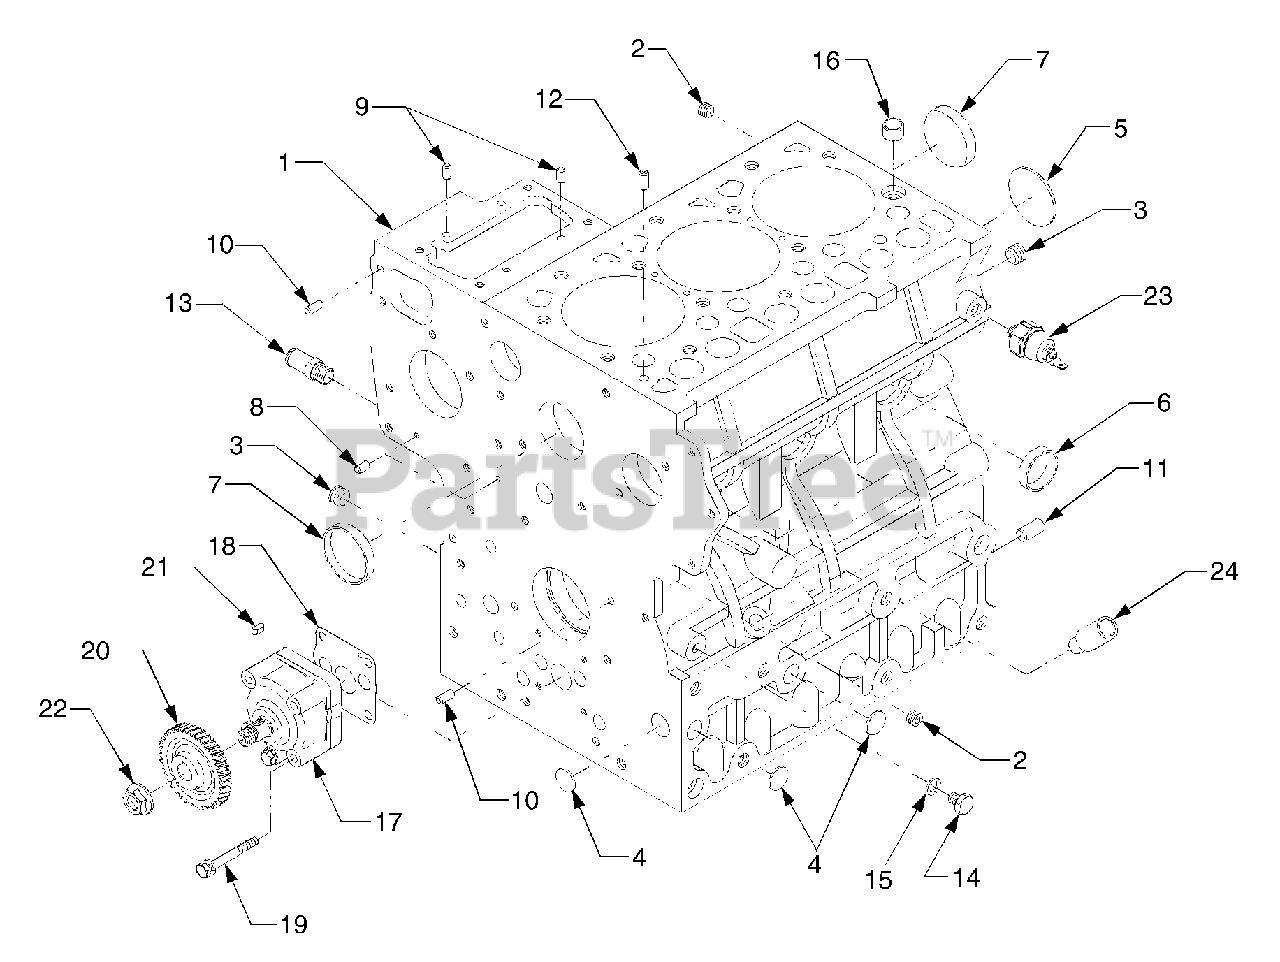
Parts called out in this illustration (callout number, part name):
1	Cylinder Block Ass'y
8	Pin, Straight
9	Pin, Straight
10	Pin, Straight
11	Pin, Straight
17	Oil Pump Ass'y
18	Gasket, Oil Pump
20	Gear, Oil Pump Drive
24	Guide, Oil Gauge
